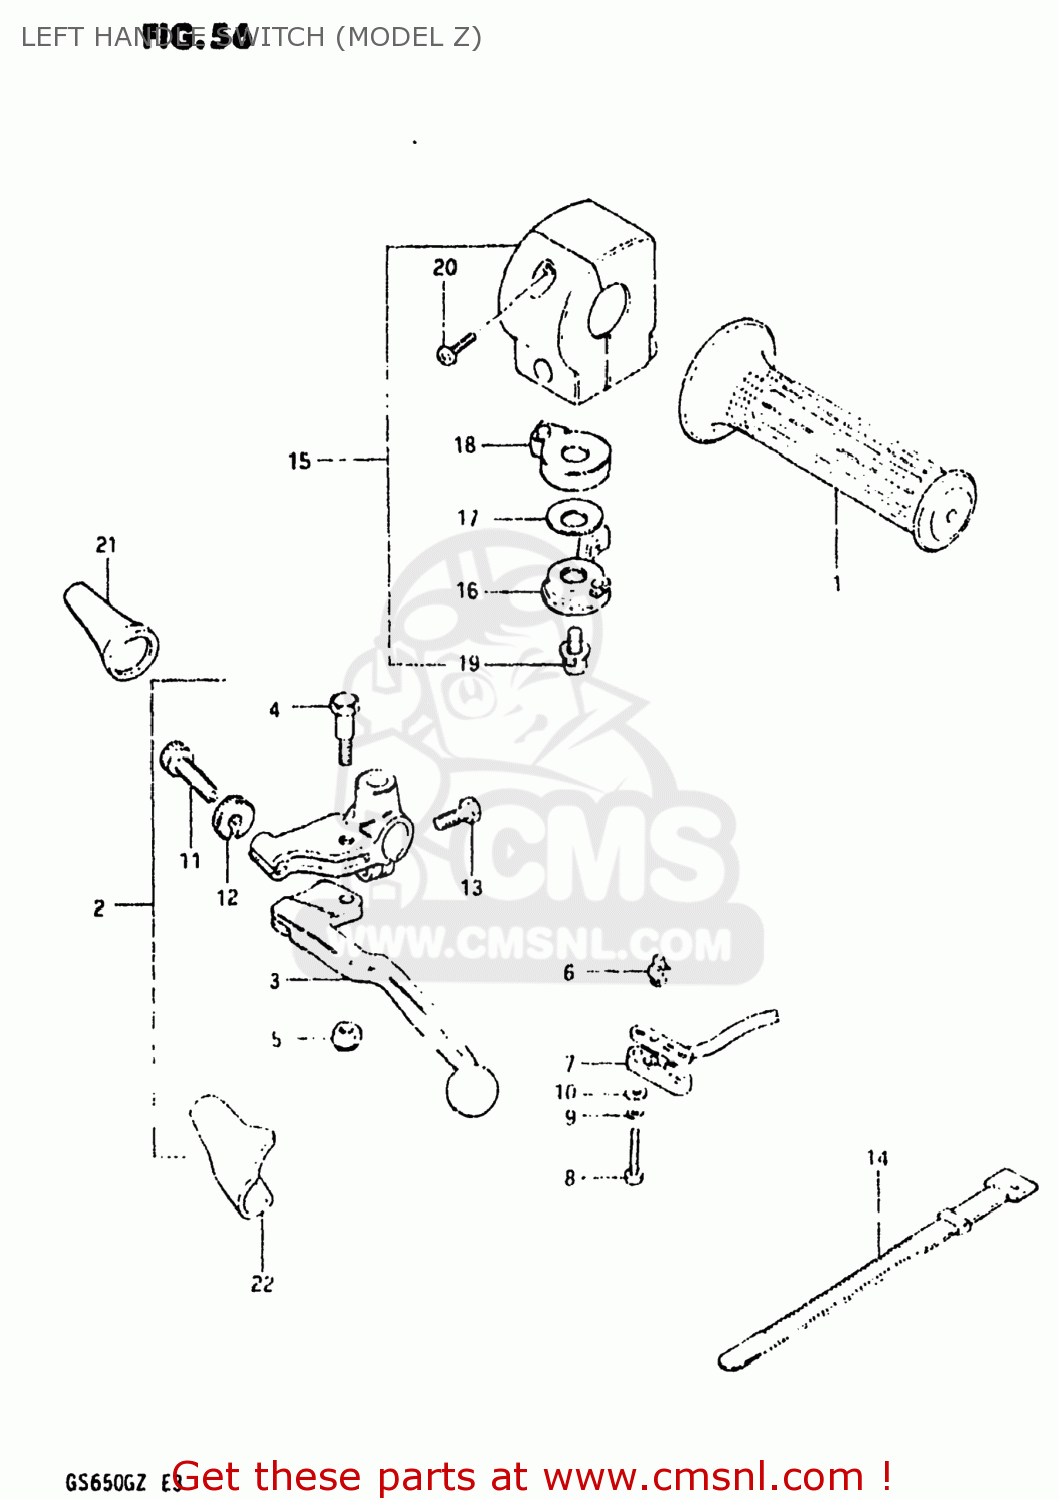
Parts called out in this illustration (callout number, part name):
1	GRIP,LEFT
2	LEVER ASSEMBLY
3	LEVER,CLUTCH
4	BOLT,LEVER
5	NUT 6MM
6	CONTACT,SWITCH
7	COVER,FR BK TERMINAL BASE
8	SCREW
9	LOCK WASHER
10	WASHER
11	ADJUSTER,CABLE
12	NUT,CABLE ADJUSTER
13	BOLT,CLUTCH LEVER HOLDER
14	CLAMP(L:120)
15	SWITCH ASSEMBLY,HANDLE,LEFT
16	LEVER,STARTER
17	WASHER,ADJUSTER
18	BODY,CHOCK
19	SCREW,CHOKE LE
20	SCREW
21	BOOT,CLUTCH CABLE
22	COVER,CLUTCH LEVER
